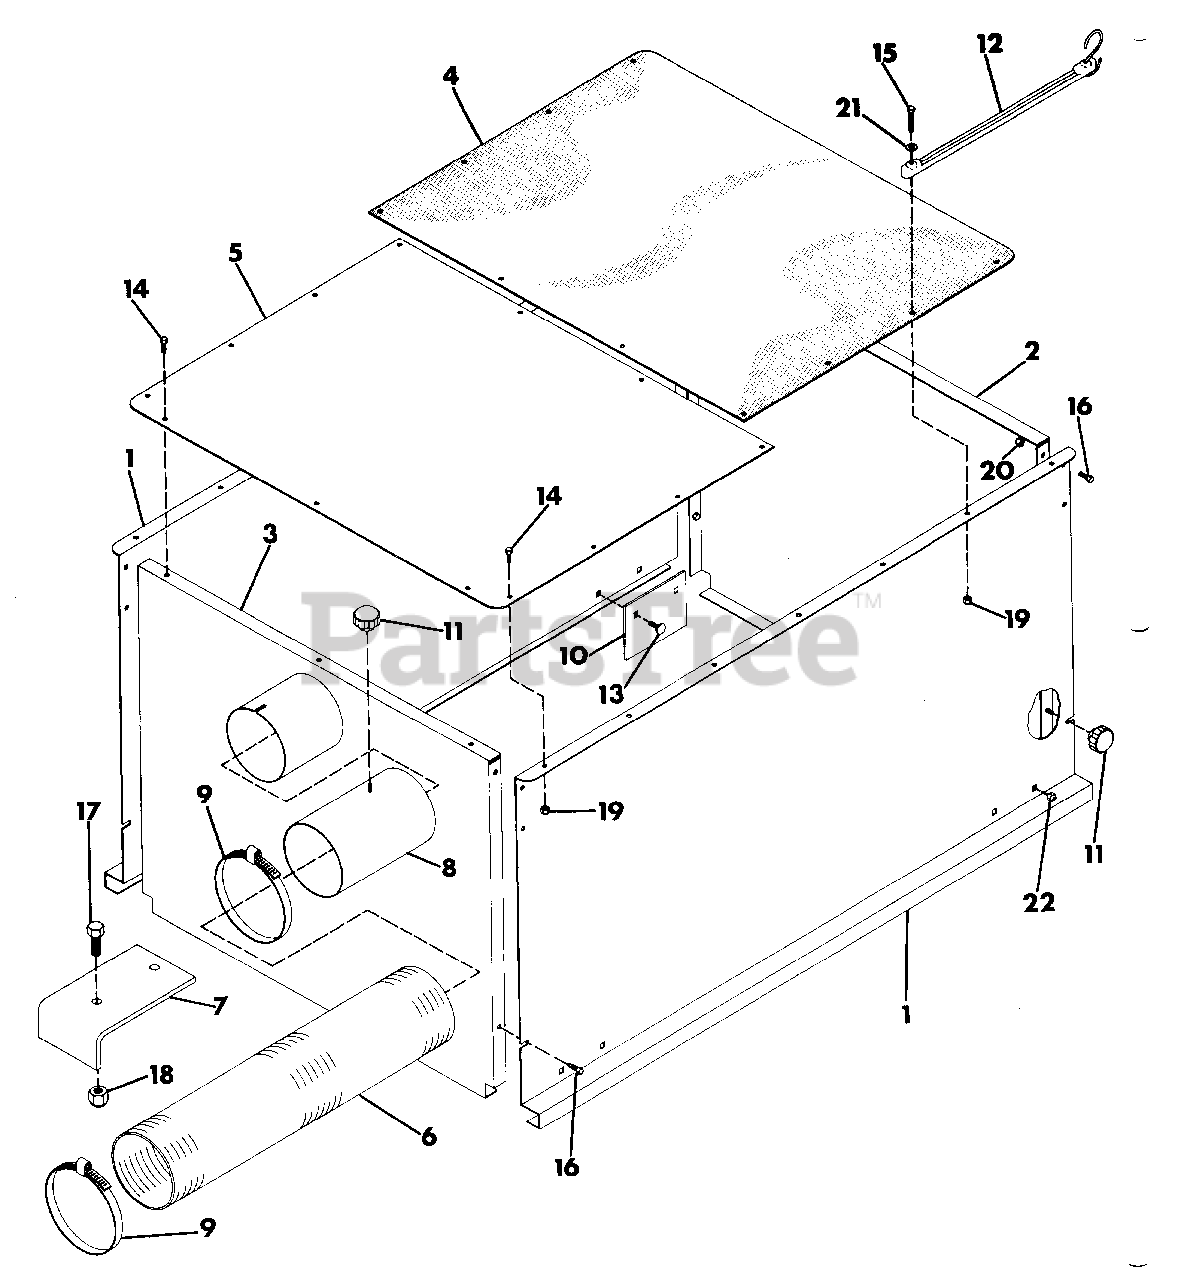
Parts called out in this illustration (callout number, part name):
1	PANEL, SIDE
2	WELDMENT, REAR GATE
3	WELDMENT, FRONT GATE
4	COVER, TOP REAR
5	COVER, TOP FRONT
6	HOSE, BLOWER TO CART
7	EXTENSION, TONGUE
8	WELDMENT, CONNECTOR TUBE
9	CLAMP
10	RETAINER, CART TOP
11	KNOB
12	STRAP, HOLD DOWN
13	BOLT, CARRIAGE 3/8-16X.75
14	BOLT, HEX 1/4-20X.75
15	BOLT, HEX 1/4-20X1.375
16	BOLT, HEX 5/16-18X.75
17	BOLT, HEX 5/8-11X1.50
18	NUT, LOCK 5/8-11
19	NUT, LOCK 1/4-20
20	NUT, LOCK 5/16-18
21	WASHER, FLAT .281X.625X.065
22	NUT, LOCK 3/8-16
NS	DECAL, GRAVELY LOGO
